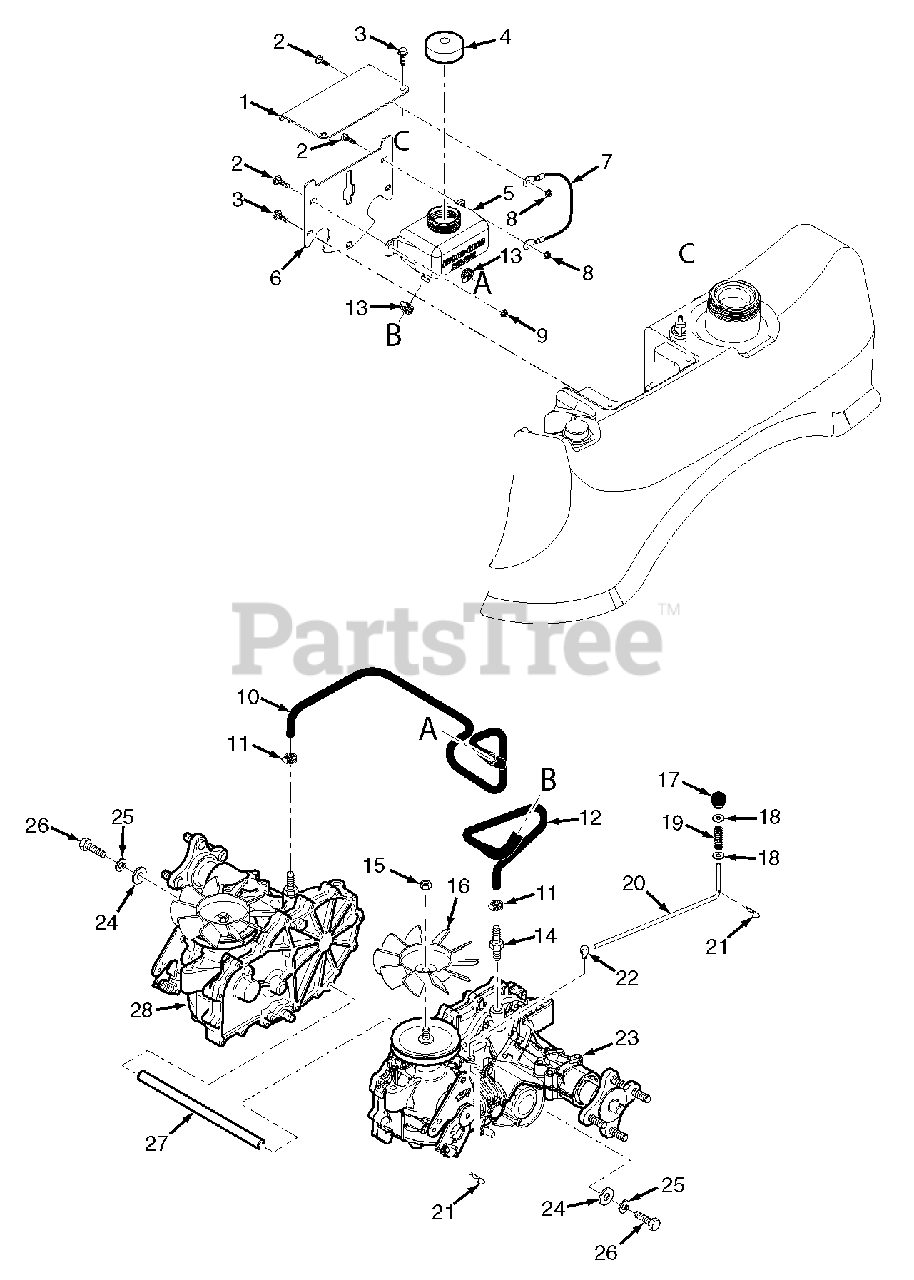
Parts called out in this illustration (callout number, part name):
1	Cover, Oil Reservoir
2	Bolt, Carriage 1/4-20 x 3/4"
3	Bolt, Serrated Flange 1/4-20 x 1/2"
4	Cap, Oil Reservoir
5	Oil Reservoir Assembly
6	Mounting Bracket, Oil Reservoir
7	Lanyard, Oil Reservoir Cover
8	Nut, Flanged Elastic Stop 1/4-20
9	Nut, Elastic Stop 1/4-20
10	Hose, RH Transaxle
11	Clamp, .69 Max Dia.
12	Hose, LH Transaxle
13	Clamp, .87 Max Dia.
14	Fitting, Transmission
15	Fan Nut
16	Fan (order through Hydro-Gear)
17	Knob, Dump Lever
18	Flatwasher, 1/4-.312 x .750 x .065
19	Spring
20	Linkage, Dump Valve
21	Hair Pin Cotter
22	Joint, Swivel
23	Transaxle, LH
24	Flatwasher, 3/8-.391 x .938 x .105
25	Lockwasher, 3/8" Spring
26	Bolt, Hex Head 3/8-16 x 2-1/4"
27	Spacer, Axles
28	Transaxle, RH
